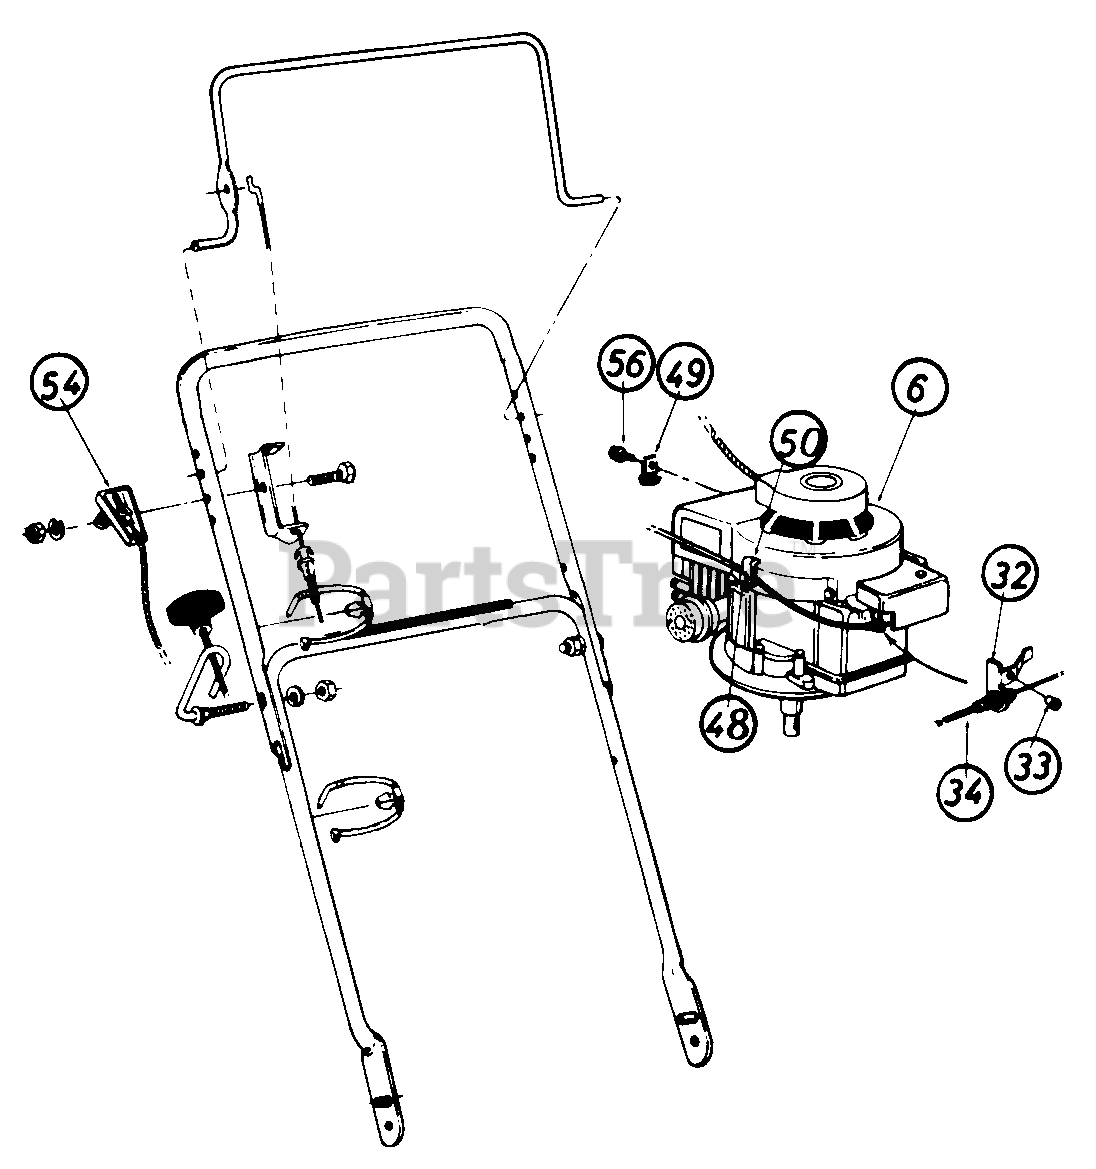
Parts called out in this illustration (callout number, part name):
6	Engine
32	Cable Bracket
33	Pop Rivet .156" Dia. x .379
34	Control Cable 43.0" Lg.
48	Hex B-Tap Scr. #1O X .38"
49	Casing Clamp
50	Casing Clamp
54	Throttle Control Ass'y. Comp.
56	Hex AB-Tap Scr. #8 x .38"
